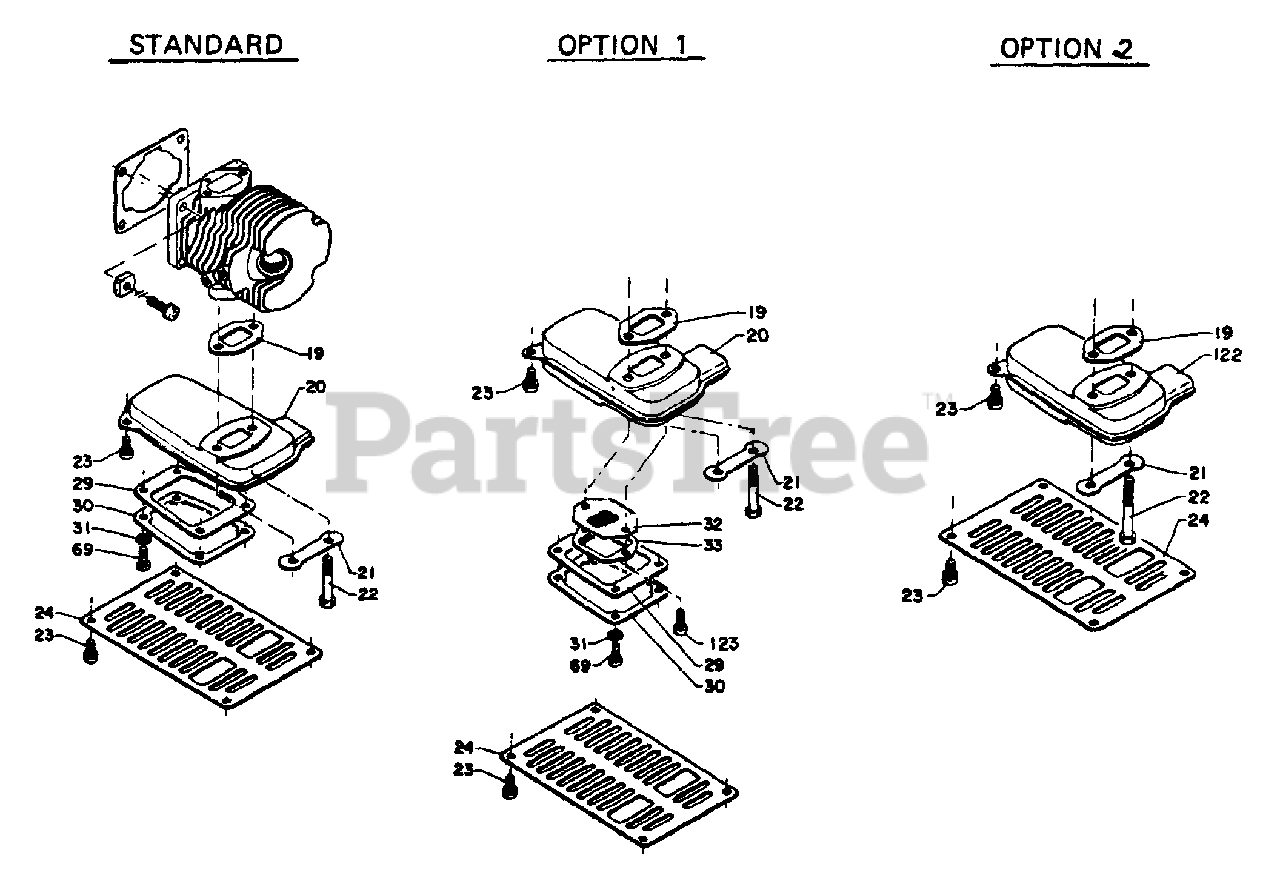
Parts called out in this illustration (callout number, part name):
19	GASKET, EXHAUST
20	CASE, MUFFLER
21	WASHER
22	BOLT - 5X30
23	SCREW - 4X10
24	COVER, MUFFLER
29	GASKET, EXHAUST
30	GASKET, EXHAUST
31	LOCKWASHER - 4
32	SCREEN, SPARK ARRESTOR
33	RETAINER, SCREEN
69	SCREW - 4X10
122	MUFFLER
123	SCREW 4 X 8
